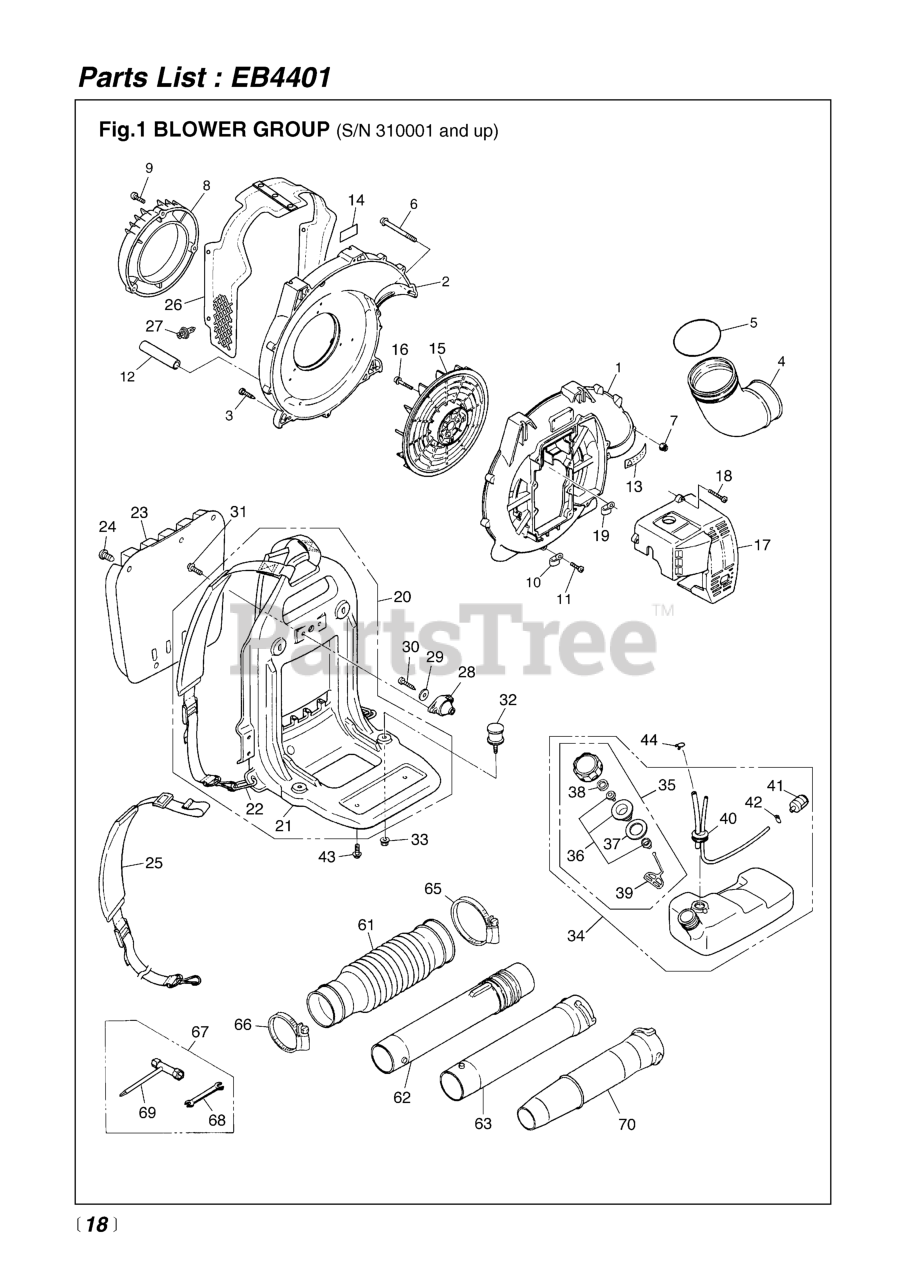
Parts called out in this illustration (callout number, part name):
1	CASE, VOLUTE
2	848-L5C-55B3
3	SCREW, M5 X 25
5	O-RING
6	SCREW, M5 X 70
7	NUT (B)
8	COVER, INLET
9	SCREW, M5 X 25
10	CLAMP
12	TUBE (RPLS. 07270-01507)
13	LABEL, CAUTION (RPLS -31910)
14	LABEL, NET
15	FAN
16	BOLT (RPLS 3405-12211)
17	COVER, ENGINE (RPLS -31611)
18	SCREW, M5 X 25
19	CLAMP
20	FRAME ASSY. (REPLACES -32001)
21	FRAME COMP. (RPLS -32100)
22	RING (REPLACES -21120)
23	PAD (RPLS -21310)
24	CLIP (RPLS 3490-21320)
25	BAND ASSY (RPLS 2750- )
26	NET COMPLETE
27	CLIP
28	DAMPER, UPPER
29	WASHER
30	SCREW
31	BOLT, M5 X 16 (RPLS -32540)
32	DAMPER, LOWER
33	NUT, M6
34	TANK ASSEMBLY (RPLS -85101)
35	CAP ASSY (RPLS -85201)
36	HOLDER (REPLACES -85230)
37	PACKING
38	FILTER
39	STOPPER
40	PIPE COMPLETE
41	FILTER ASSY
42	CLIP (REPLACES 2841-31280)
43	SCREW, M5 x 12
44	CLIP
61	HOSE (RPLS 2750-51110)
62	SWIVEL-JOINT (REPLACES -51200)
63	PIPE, STRAIGHT
65	CLAMP (RPLS 3490- )
66	CLAMP (RPLS 3050-13230)
67	TOOL SET
68	SPANNER, 8 X 10 (RPLS 2540- )
70	KIT, NOZZLE (USE 2756-51221)
